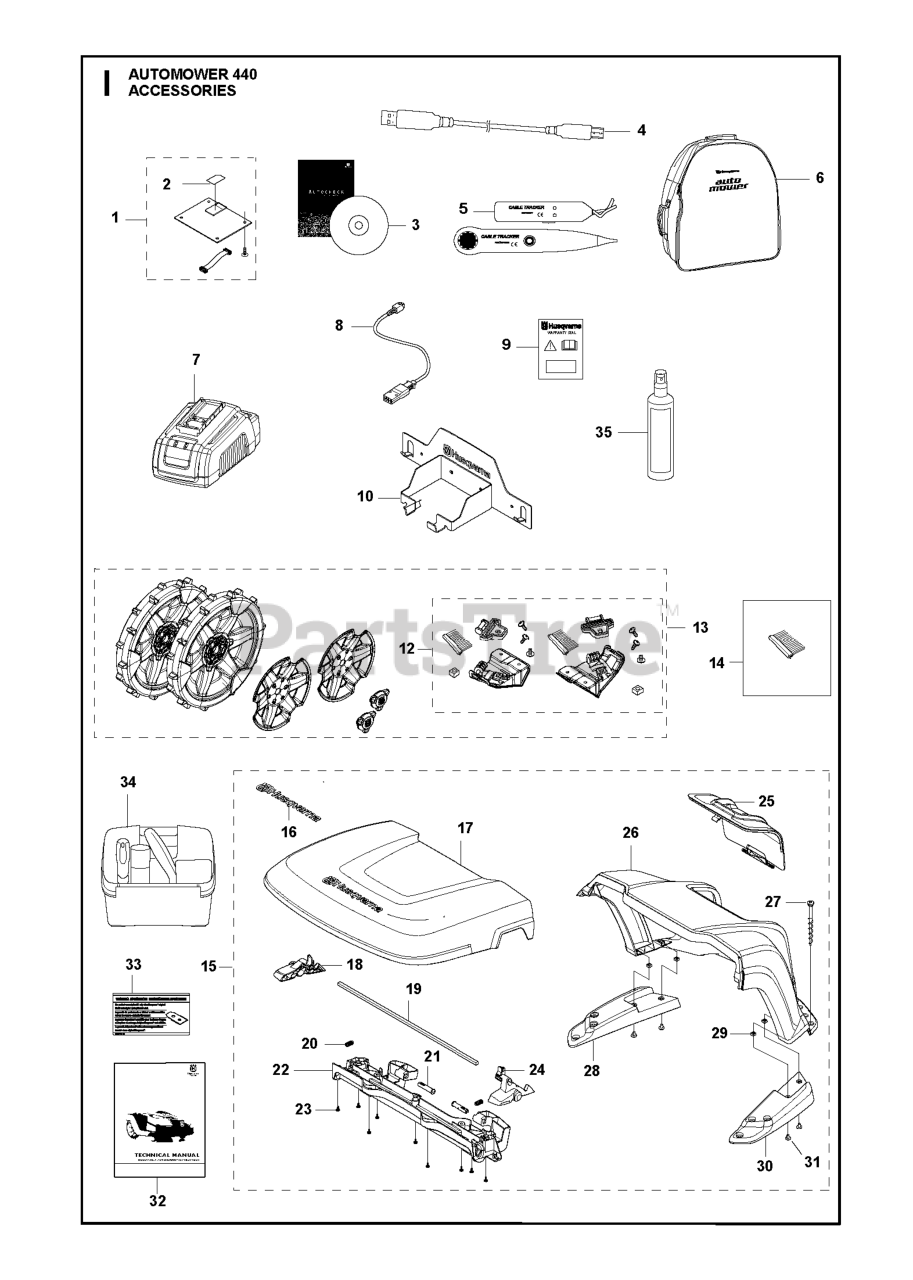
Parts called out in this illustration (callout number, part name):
1	CONNECT MODULE 2G / 3G
3	DVD AUTOCHECK EXP SERVICE
4	CABLE WHITE ALT GREY
5	TEST EQUIPMENT
6	BAG
7	CHARGER BATTERY TEST
8	CABLE ASSY QUICK CHARGER
9	LABEL WARRANTY SEAL DEALER
10	MISC. BLISTER WALL HANGER
12	BRUSH KIT 430/450
13	REAR WHEEL KIT W/ BRUSHES
14	WHEEL BRUSH REFILL KIT
15	430/450 HOUSE KIT
16	DECAL.HUSQVARNA.210MM
17	KIT LID - AUTOMOWER HOUSE
18	HANDLE RELEASE LEFT
19	ROD
20	SPRING SPRING CAP
21	HINGE PIN
22	BEAM
23	SCREW 14MM
24	HANDLE RELEASE RIGHT
25	HATCH
26	COVER BASE P2 HOUSE
27	SCREW KIT CS
28	SUPPORT BASE LEFT
29	NUT
30	SUPPORT BASE RIGHT
31	SCREW IHPANM M6X25 4.6 ZP-BC
33	ORIGINAL PARTS STICKER
33	DECAL WARNING ORIGINAL BLADE E
34	CLEANING AND MAITENANCE KIT AM
35	AUTOMOWER ACCY
